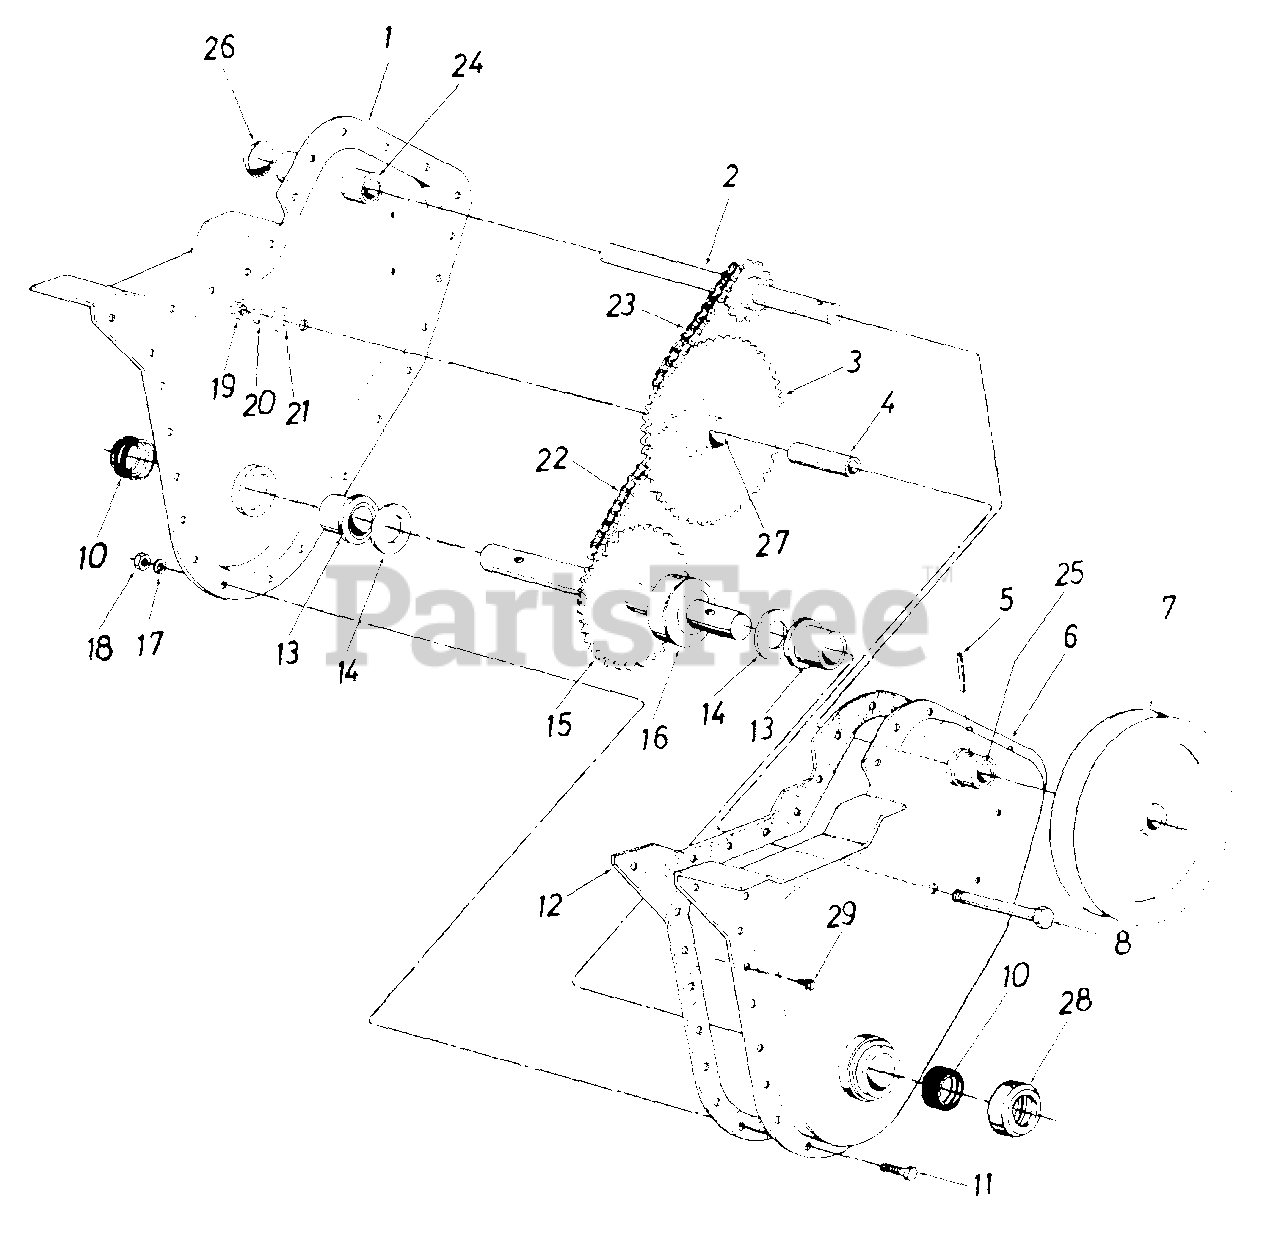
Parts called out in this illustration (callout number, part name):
1	Chain Case Ass'y. - R.H.
2	Input Shaft Ass'y.
3	Hub and Sprocket Ass'y.
4	Bearing Inner Race
5	Spring Pin Spiral 1/4" Dia. x 1.50" Lg.
6	Chain Case Ass'y. - L.H.
7	Pulley - Chain Case 5 1/2 x 1/2
8	Hex Bolt 3/8-24 x 2.50" Lg.
11	Hex Bolt 1/4-28 x .625" Lg.
12	Gasket
13	Flange Brg. .879 I.D.
14	Fl-Wash. .88 I.D. x 1.50 O.D. x .030
15	Tine Shaft Ass'y.
16	Spacer 7/8" I.D. x 2.0" O.D. x .68" Lg.
17	L-Wash. 1/4" Scr.
18	Hex Nut 1/4-28 Thd.
19	Hex Nut 3/8-24 Thd.
20	L-Wash. 3/8" Scr.
21	Bell-Wash. .406 I.D. x 1.130 O.D.
22	Chain #420 - .50" Pitch x 38 Links
23	Chain #35 - .375" Pitch x 50 Links
24	Bearing .62" I.D. x .813 O.D. x 1.31
25	Bearing .62" I.D. x .813 O.D. x 2.06
26	Expansion Plug 13/16" Dia.
29	Hex Wash. Hd. Self-Tap Scr. 1/4-20 x .50" Lg.
